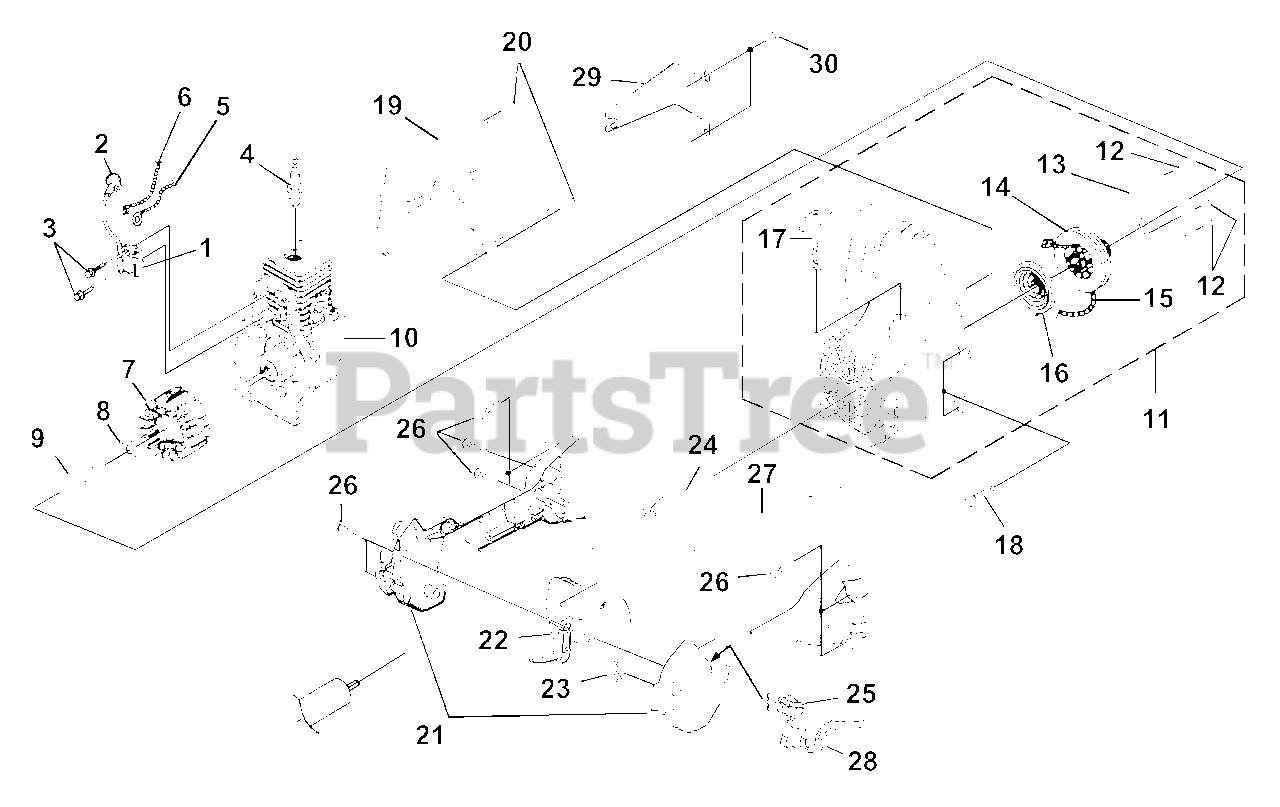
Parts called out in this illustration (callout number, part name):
1	MODULE-Ignition
2	TERMINAL & COVER
3	SCREW-Taptite (8-32 X 1")
4	SPARK PLUG - Resistor
5	LEAD-Ground
6	LEAD-Electrical
7	ROTOR KIT
8	WASHER-Flat
9	CONNECTOR-Drive
10	SHORT BLOCK
11	COMPLETE STARTER ASSEMBLY
12	SCREW-Taptite (8-16 X 1/2")
13	BAFFLE-Air
14	PULLEY-Starter
15	ROPE-Starter (42")
16	SPRING & CONTAINER
17	GRIP-Starter
18	SCREW-Taptite (10-24 X 3/4")
19	HOUSING-Rear Kit
20	SCREW-Taptite (10-14 X 7/8")
21	CONTROL HANDLE ASSY.
22	TRIGGER-Throttle
23	SPRING
24	THROTTLE INTERLOCK
25	SWITCH
26	SCREW-Taptite (10-14 X 1")
27	CABLE-Throttle
28	LEAD-Electrical
29	GUARD-Muffler
30	SCREW-Thread Forming (10-14 X 1/2")
